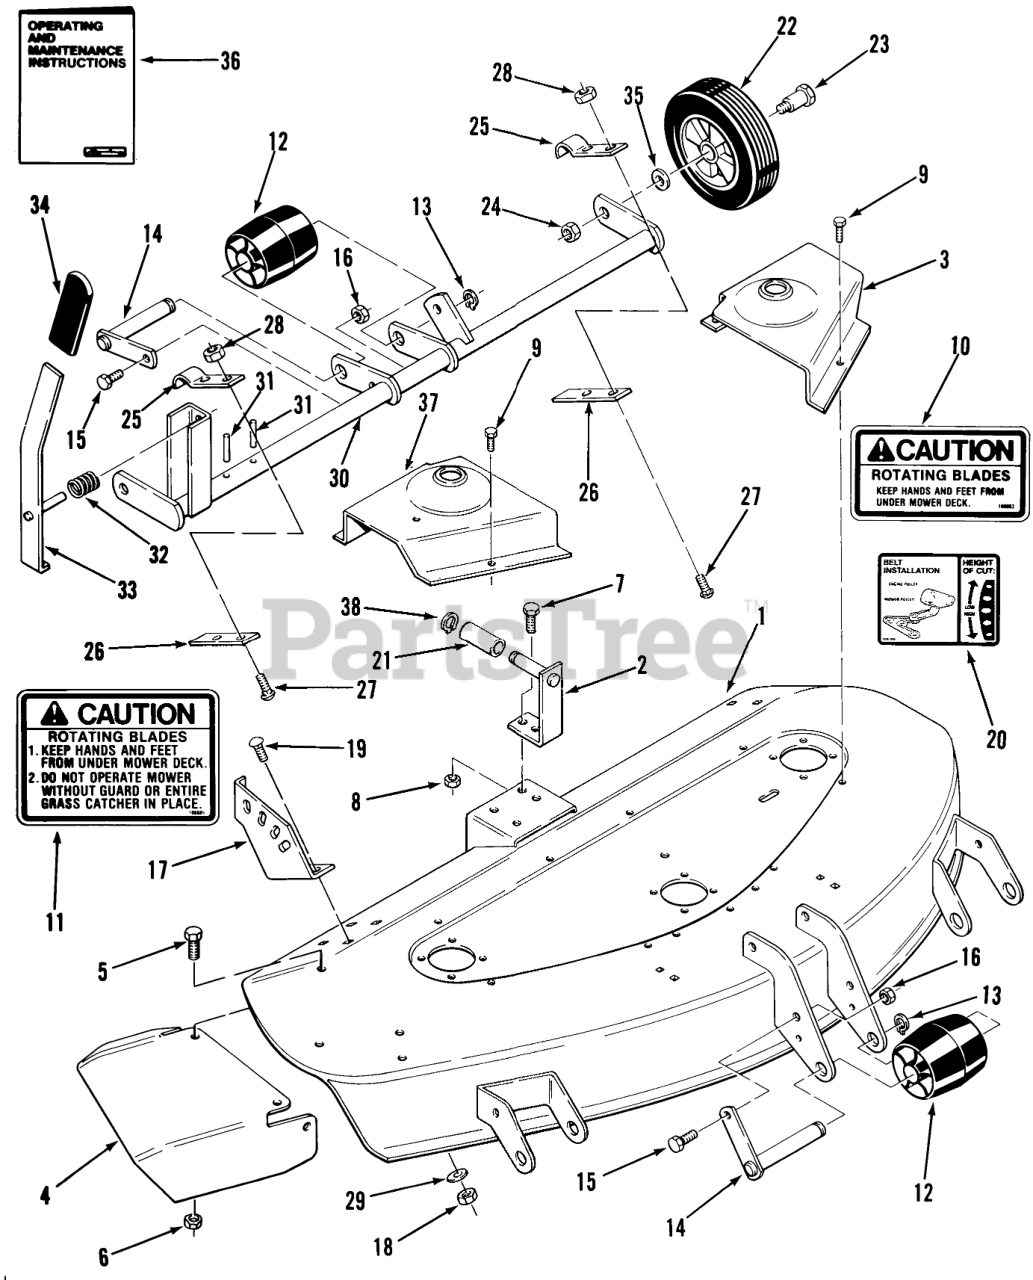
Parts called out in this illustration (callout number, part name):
1	Deck
2	Bracket Guide
3	COVER-BELT LH R
4	Chute Extension
5	Bolt
6	Nut
7	BOLT
8	Nut
9	Bolt
10	Caution Decal
11	DECAL
12	Roller
13	Retaining Ring
14	Roller Shaft
15	H H C S
16	Nut
17	Quadrant
18	Nut
19	Bolt-Carriage
20	DECAL-HEIGHT BELT
21	SPACER
22	Wheel 6 x 1.75
23	BOLT-SHOULDER
24	Nut
25	Machine Bolt
26	Bar
27	Bolt
28	NUT
29	Washer
30	Gage Wheel Support
31	PIN-SPIROL
32	SPRING-COMPRESSION
33	LEVER ASSY R
35	WASHER
36	Operating and Maintenance Instructions
37	COVER-BELT RH R
38	Snap Ring
